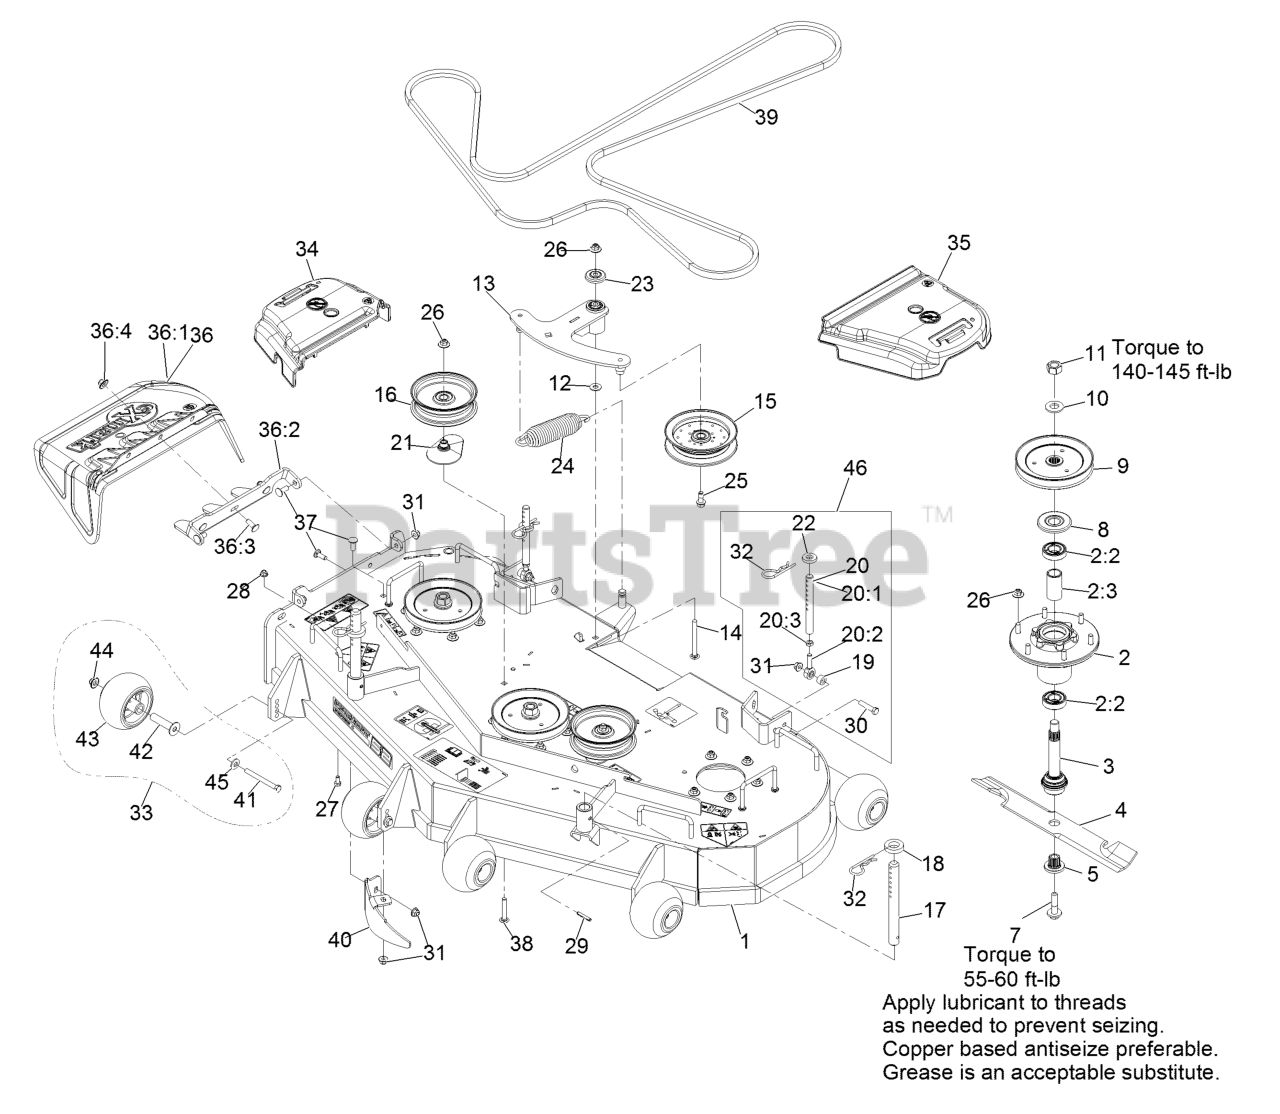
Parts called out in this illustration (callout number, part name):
1	ASM, DECK W/ DECALS, 52"
2	ASM-CUTTER HSG WITH BEARINGS
2:2	BEARING-BALL
2:3	SPACER-BEARING
3	ASM-SPINDLE AND SEAL
5	BUSHING,SPLINED
7	SCREW,SEMS 1/2-20 X 2.19
8	GUARD,BEARING TOP .989
9	SHEAVE,BLADE DRIVE 6.50
11	NUT-HEX
12	WASHER-FLAT
13	ASM, DECK IDLER
14	SCREW-CARR
16	IDLER-PULLEY, FLAT
17	ROD,DECK SUPPORT
18	SPACER-DECK SUPPORT
20:1	LINK,SUPPORT
20:2	BALLJOINT
20:3	NUT-HJ
21	SPACER-PULLEY
23	GUARD-TOP
24	SPRING-EXTENSION
25	SCREW-HFH
26	Nut-Nyloc 3/8-16 Flg
27	SCREW-HH
28	NUT-HF, NI
30	SCREW-HH
31	NUT-HF, NI
32	PIN,HAIR COTTER
33	KIT, ANTI-SCALP ROLLER
34	COVER-BELT, RH
35	COVER-BELT, LH
36	ASM,DISCHARGE CHUTE
36:1	CHUTE,DISCHARGE
36:2	BRACKET,DISCHARGE CHUTE
36:3	SCREW-CARR
36:4	Nut-Nyloc 3/8-16 Flg
37	SCREW-CARR
38	BOLT-CARR, SHORT NECK
39	BELT, DECK DRIVE
40	BAFFLE-DOGLEG, LZ-VT52
41	SCREW-HH 3/8-16 X 3 3/4 GR 8
42	AXLE, ROLLER
43	ROLLER-SCALP, ANTI
44	Nut-Nyloc 3/8-16 Flg
45	WASHER-BELLEVILLE
46	KIT,SUPPORT LINK W/PIN
